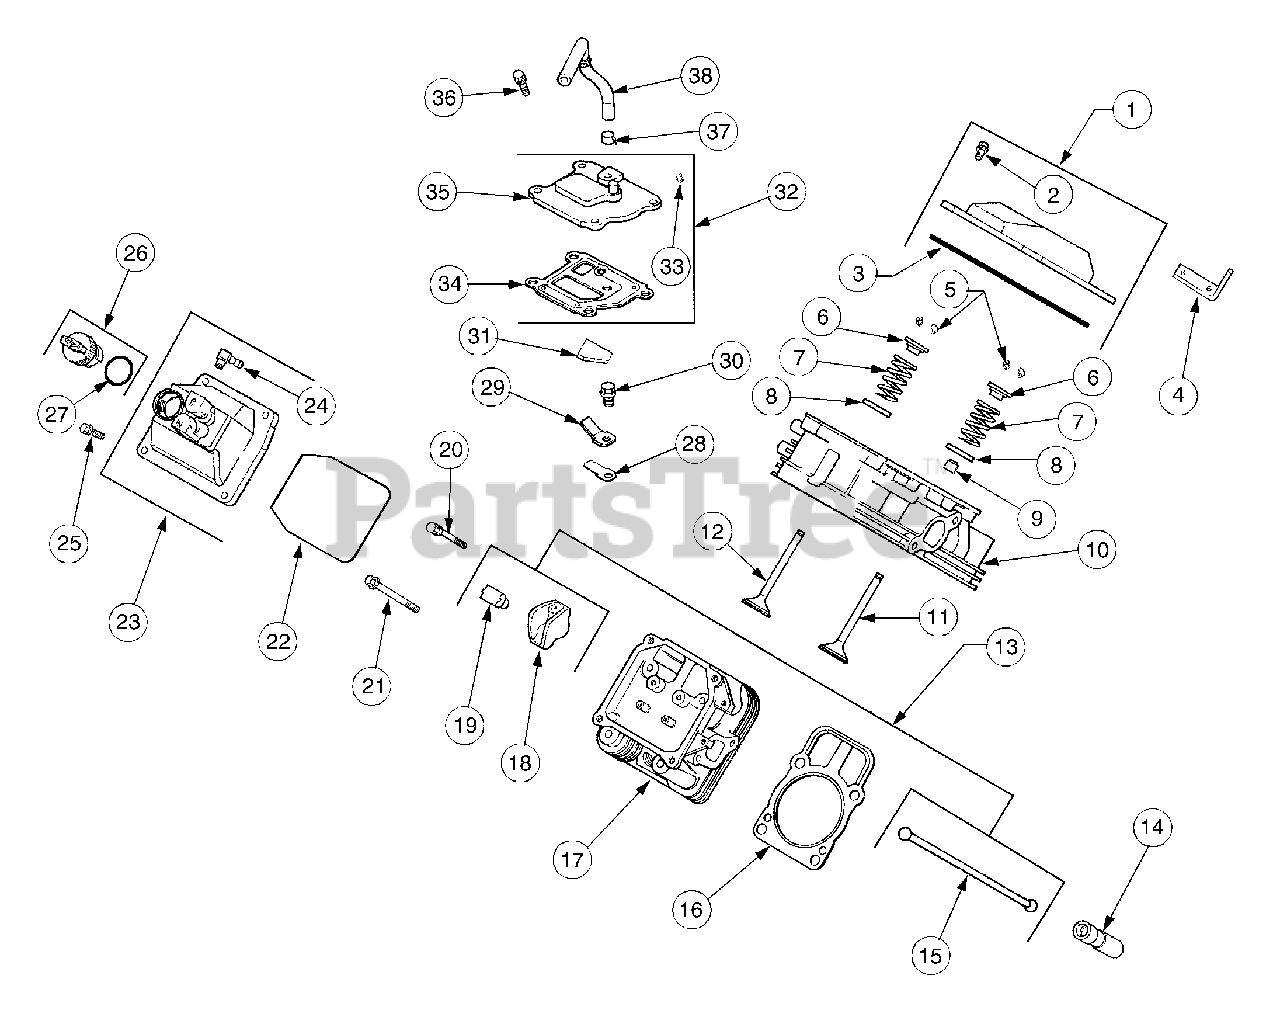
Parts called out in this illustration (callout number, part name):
1	Kit, Valve Cover
2	Screw, Shoulder
3	O-Ring, Valve Cover
4	Strap, Lifting
5	Kit, Retainer
6	Cap, Valve Spring
7	Spring, Valve
8	Retainer, Spring
9	Seal, Valve Stem
10	Head Assembly, #1 Cylinder
11	Valve, Intake Std
12	Valve, Exhaust Std
13	Kit, Valve Train
14	Lifter, Valve
16	Gasket, Cylinder Head
17	Head Assembly, #2 Cylinder
19	Pivot, Rocker Arm
20	Screw, Hex Flng, M6 x 1.0 x 34
21	Screw, Hex Flng, M10 x 1.5 x 90
22	O-Ring, Valve Cover
23	Cover, Fuel Pump Vlv
24	Connector, 90°.
25	Screw, Shoulder
26	Cap Assembly, Oil Fill
27	O-Ring
28	Reed, Breather
29	Retainer, Breather Reed
30	Screw, Hex Flng, M5 x 0.8 x 10
31	Filter, Breather
32	Kit, Breather
33	Plug, Allen Hd 1/8 Pipe
34	Gasket, Breather
35	Cover, Breather
36	Screw, Hex Flng M6 x 1.0 x 20
37	Clamp, Breather
38	Hose, Breather
